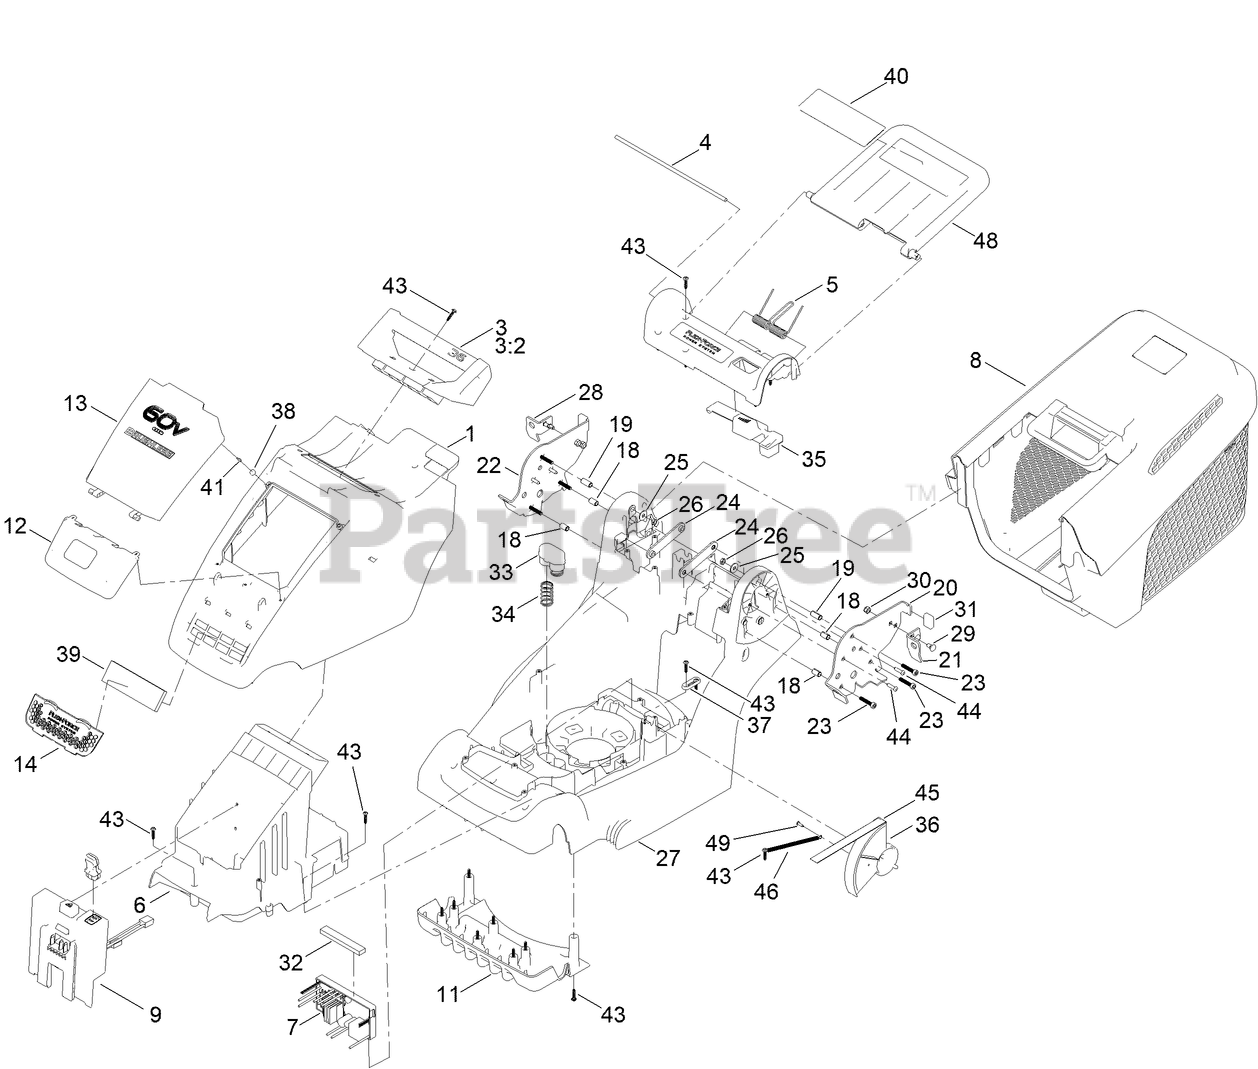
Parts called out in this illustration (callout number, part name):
1	TOP COVER
3	CARRY HANDLE
3:2	ARTWORK - 36CM
4	ROD, REAR FLAP
5	SPRING, REAR DEFLECTOR
6	Guard, Flywheel
7	DRIVER-MOTOR, 36CM
8	GRASS BOX ASM
9	BATTERY INTERFACE ASSEMBLY
11	FRONT FINS
12	BATTERY DOOR LOWER, PRINTED
13	BATTERY DOOR, PRINTED
14	AIR INLET GRILL-TORO
20	MOUNT PLATE, HANDLEBAR, LEFT
21	BRACKET, V-STOW, LEFT
22	MOUNT PLATE, HANDLEBAR, RIGHT
24	BRACE-BAR
25	WASHER
27	HOC COVER
28	BRACKET, V-STOW, RIGHT
29	BOLT, CARRIAGE, M6X1
30	NUT, NYLOC, M6X1
31	RUBBER FOOT-V-STOW
32	FILTER, AIR-CONTROL BOARD
33	BATTERY SPRING COVER
34	SPRING, BATTERY EJECT
35	HOC BUTTON, 36CM
36	HOC DIAL
38	MAGNET
39	Cover, Exhaust-Right
40	DECAL SAFETY 60V
41	PT SCREW 3MM X 10MM CSK
44	SCREW-TORX
45	DECAL - HOC
46	SPRING
48	REAR DEFLECTOR, TORO
